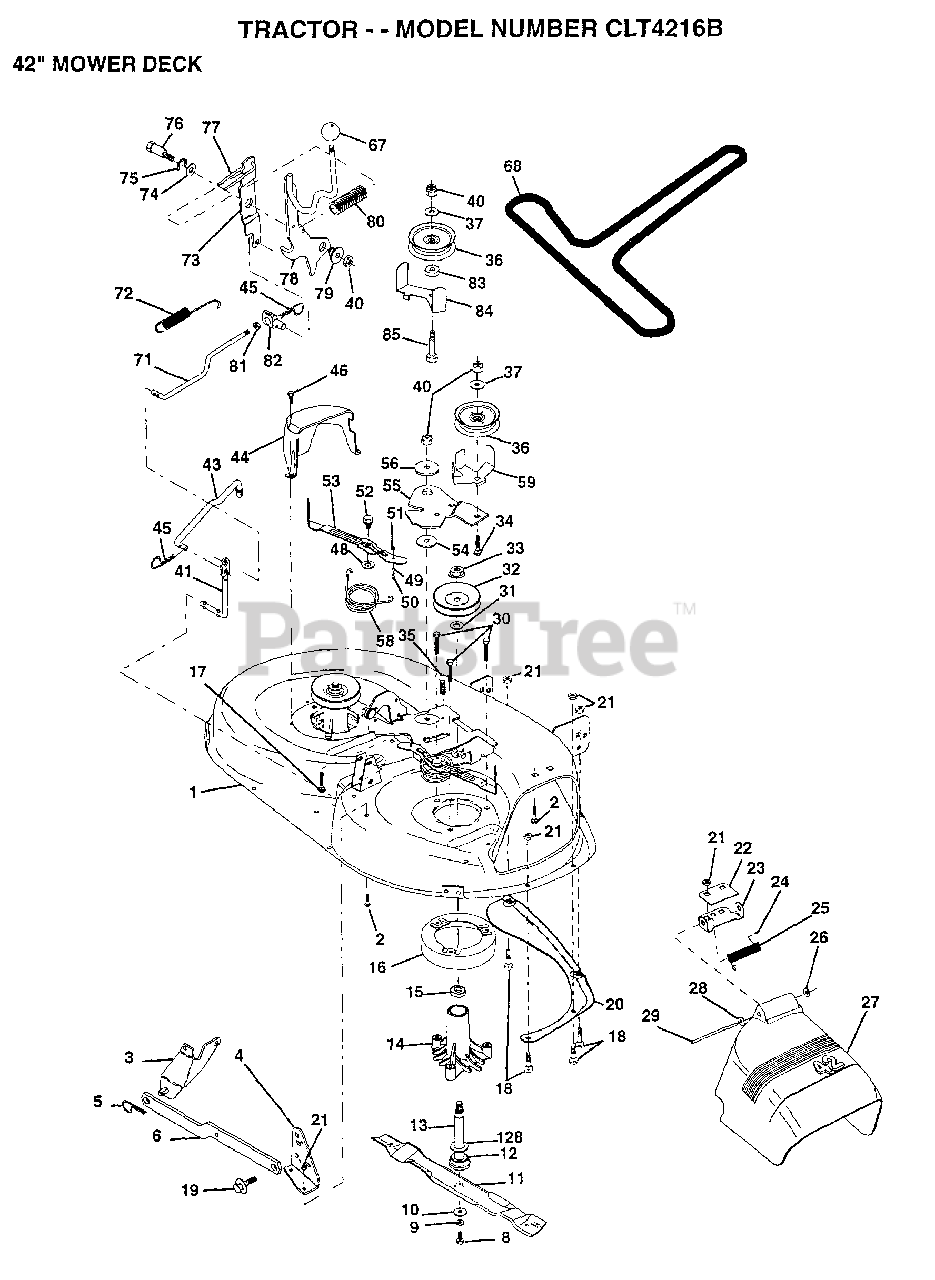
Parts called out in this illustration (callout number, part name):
1	DECK.WELD.42.
2	BOLT
3	BRKT ASM SWAY BAR
4	BRKT DECK SW BAR
8	BLADE BOLT
10	WASHER.HARD.BLADE
11	"BLADE.42"" HIPERF"
12	BEARING.BALL
14	HSG ASM MANDREL
15	BEARING
16	STRIPPER RND MWR
17	BOLT RDHD 3/8-16
18	BOLT
19	BOLT SHD 5/16-18
22	STIFFENER BRKT
23	DEFLECTOR BRKT
24	CAP-SLEEVE LT
25	SPRING TORSION
26	NUT PUSH M
27	DEFLECTOR.SHIELD
28	WASHER
29	HINGE ROD
31	WASHER
32	PULLEY.MANDREL.42
34	BOLT
35	XMAS TREE FASTNER
36	FLAT IDLER PULLEY
37	WASHER
41	PIVOT ROD
43	ROD CLUTCH W/NIBS
44	GUARD MAND LH BLK
45	RETAINER M
46	SCREW.1/4-20X5/8
48	HARD SMALL WASHER
50	SHOULDER BOLT
51	LOCKNUT
52	BOLT.SHLD.5/16-18
53	BRAKE PAD ARM ASM
54	HARDENED WASHER
56	SPACER RETAINER
58	SPRING TORSN BRAK
59	GUARD IDLER TUV
67	KNOB T (1/2-HOLE)
68	BELT.V.T-PATH
71	ROD CLUTCH 38/42
72	RETURN SPRING
73	CLUTCH ARM SECOND
74	WASHER
75	RING
76	SHOULDER BOLT
77	SPRING KEEPER
79	BUSHING
80	SPRING.CLUTCH.MWR
81	NUT
82	TRUNION ADJ
83	WASHER
85	BOLT RDHD 3/8-16
128	WASHER.FELT.
